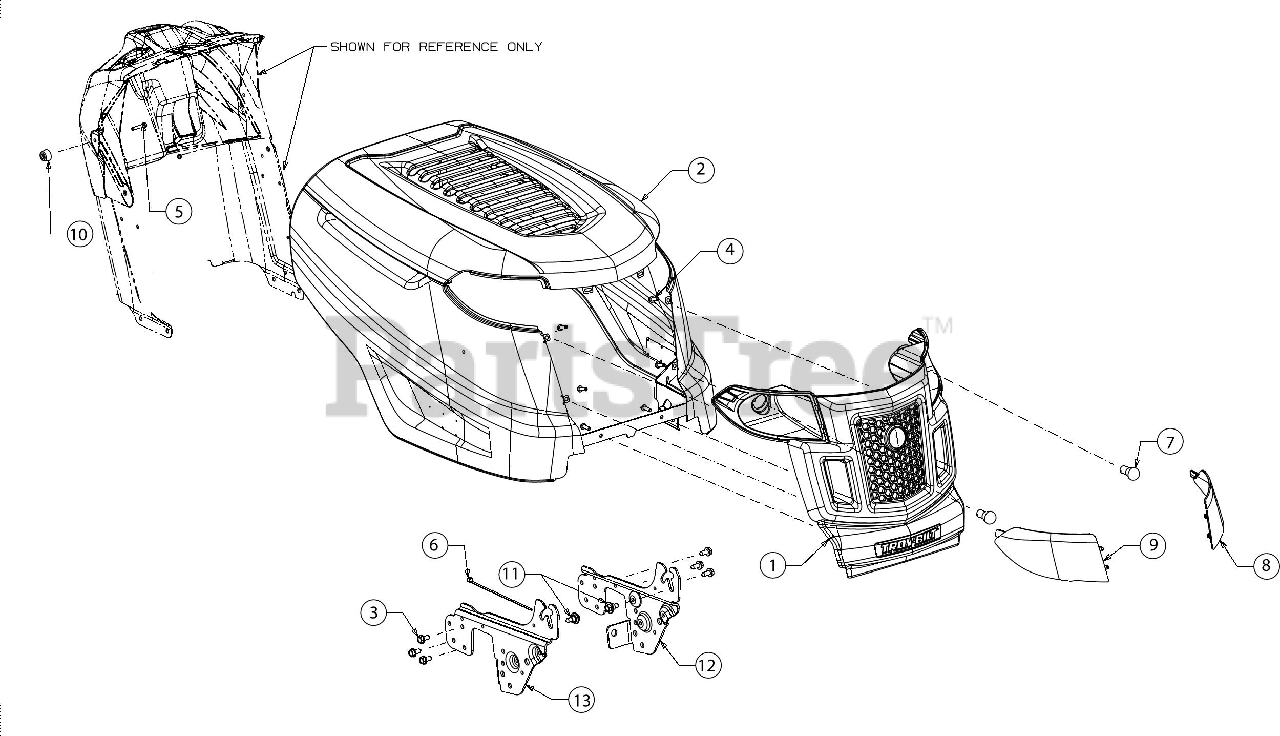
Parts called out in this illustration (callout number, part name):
1	GRILLE ASSEMBLY (TROY-BILT)
1	LABEL-TROYBILT/GEAR
2	HOOD ASSEMBLY (K STYLE)
2	HOOD W/LOUVERS
3	SCREW 5/16-18 X .750
4	SCREW 1/4 X .750
5	SCREW #12 X 1.15
6	CABLE TIE 7",1"
7	MINIATUURE BULB 12V
10	DASH BUMPER K STYLE
11	SHOULDER SCREW .43X.29X5/16-18 TT
12	SUPPORT BRACKET (LH)
13	SUPPORT BRACKET (RH)
